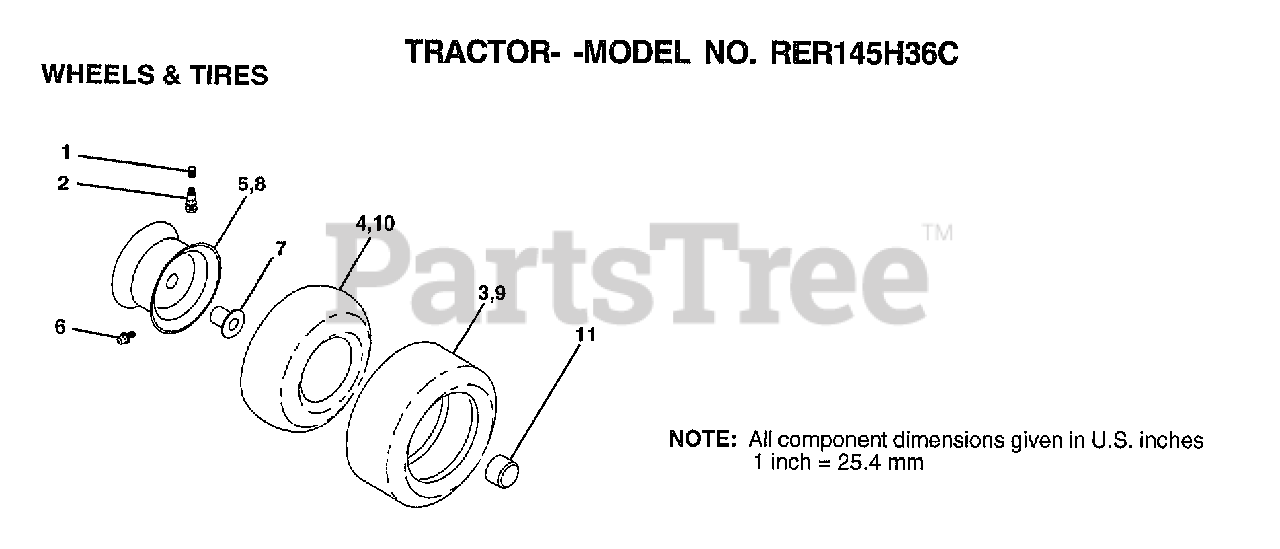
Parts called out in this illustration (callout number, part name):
1	VALVE CAP
2	VALVE STEM LT
4	TUBE.5.3/4.5/6
5	"RIM ASM 6"" FRT"
6	FITTING LT
7	"FLANGE, BEARING"
8	"RIM AS 8"" REAR"
9	TIRE.20X8-8
10	TUBE.18X9.5-8
11	HUB CAP
